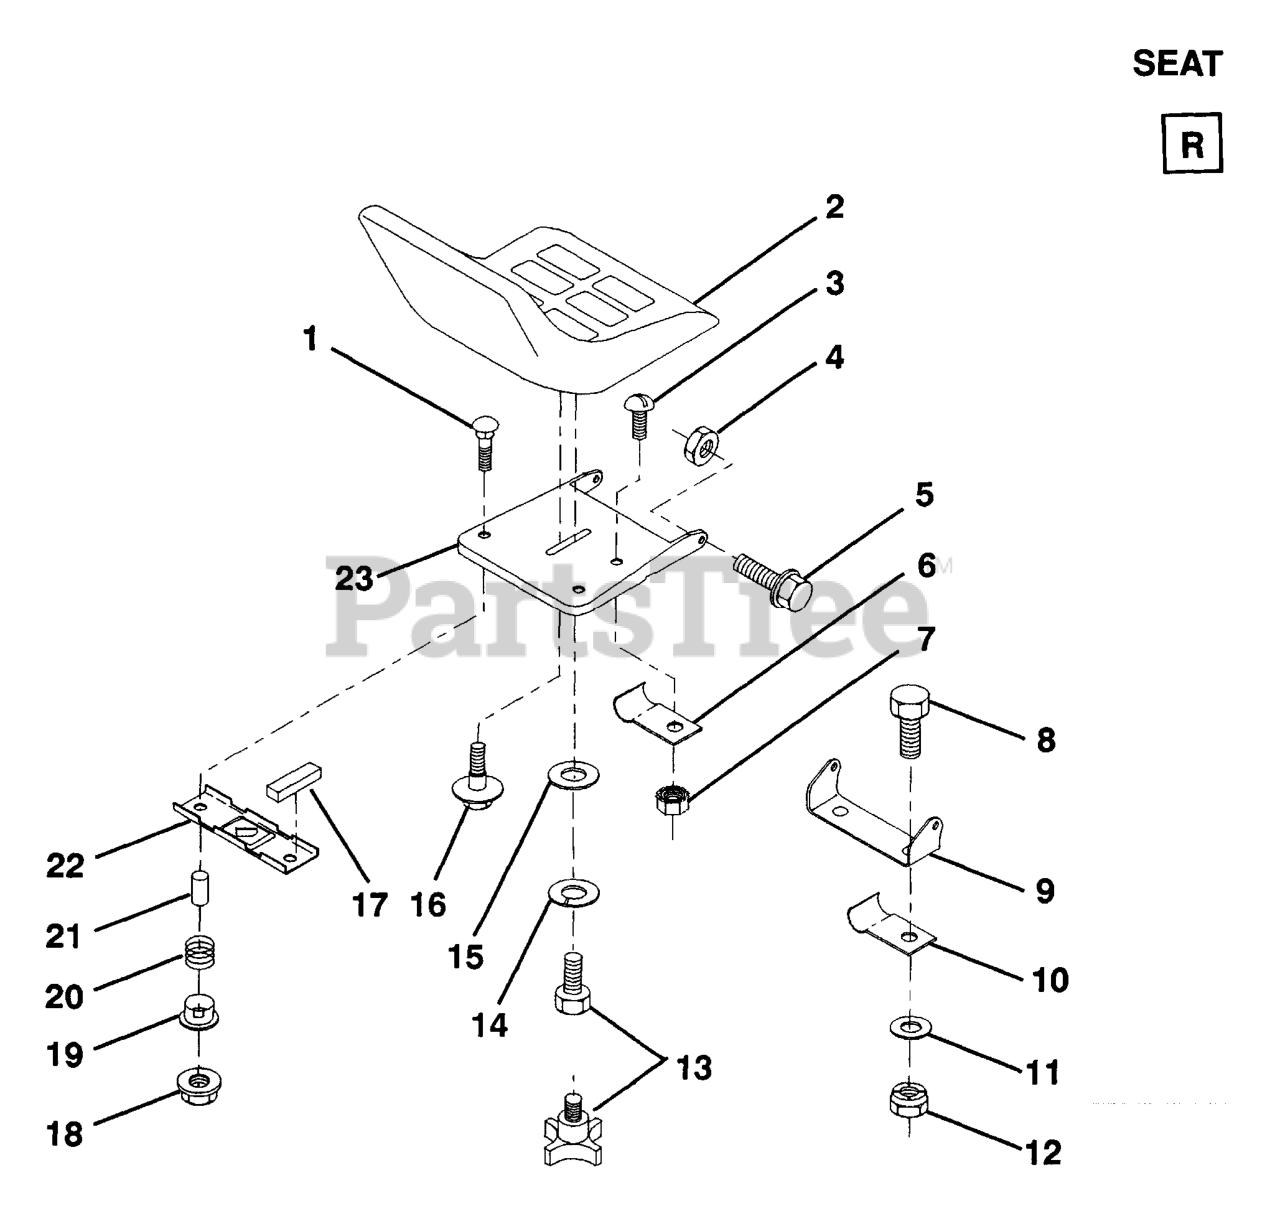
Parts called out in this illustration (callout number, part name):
2	SEAT
4	LOCKNUT
5	BOLT, SHOULDER LT
7	Nut, Hex, Keps #10-32 UNF
9	BRKT,SEAT PIVOT
10	CLIP,INSULATOR
11	WASHER
13	KNOB 1/2" YT
13	BOLT
14	LOCKWASHER
16	BOLT,SHOULD
17	STRIP FORM
18	NUT.CROWNLOCK.1/4
21	SPACER SPLIT
22	BRKT SWITCH
